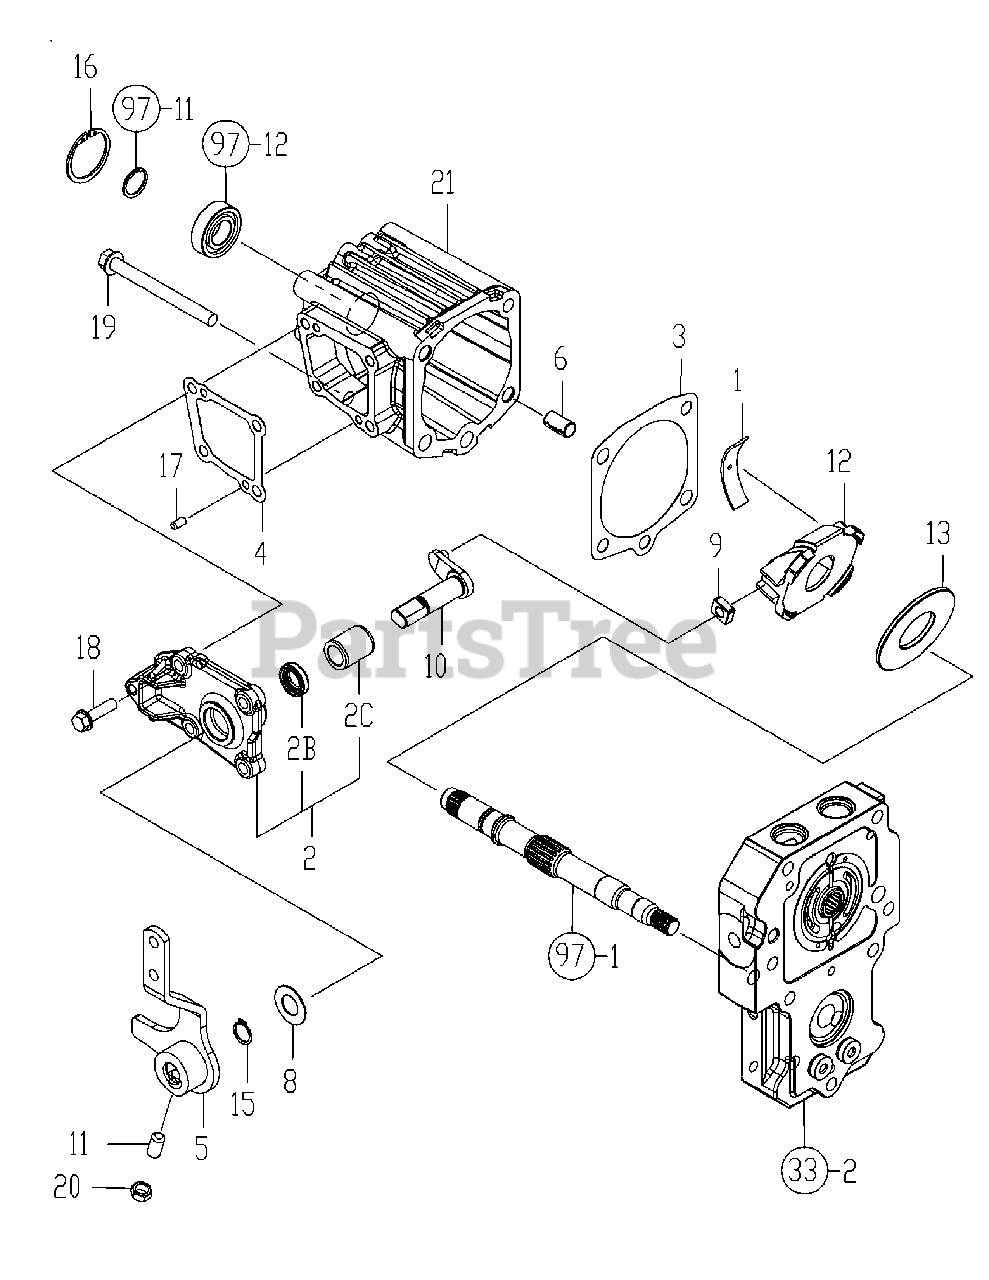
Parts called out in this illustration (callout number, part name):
1	THRUST METAL(DDR16
2	SIDE COVER ,MOTOR
3	PACKING, MOTOR CASE
4	PAKING (SIDE COVER
5	SECOND LEVER CMP
6	PIN, KNOCK 12X22
8	WASHER 17X32X1
11	SET SCREW 10X20
19	BOLT, 10 X 105
21	MOTOR CASE K93
